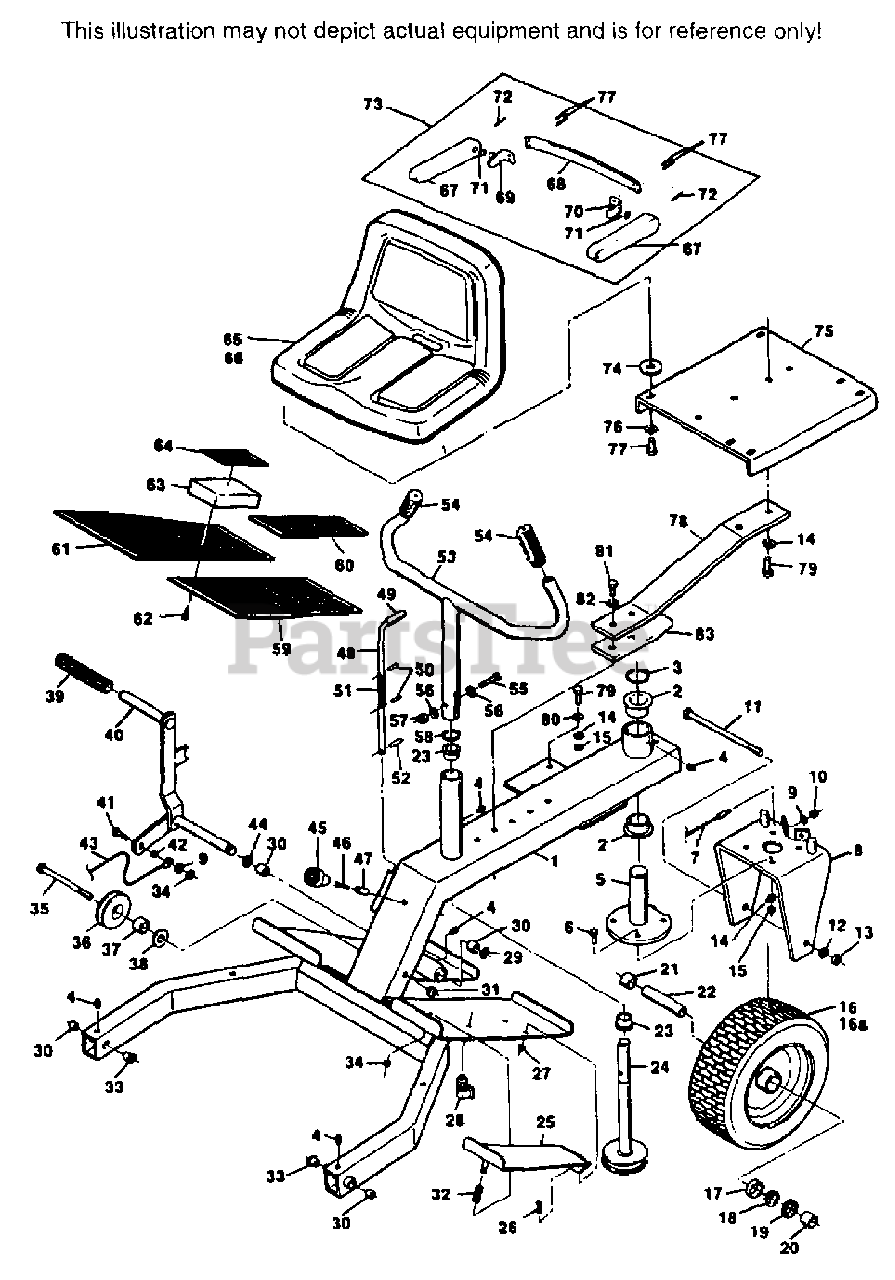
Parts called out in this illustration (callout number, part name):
1	STEERING FRAME
2	BRONZE BEARING
3	RETAINING RING, 1-1/8 EXT. BASIC
4	GREASE FITTING, 1/4-28 STR.
5	REAR WHEEL PIVOT
7	STEERING CABLE
8	REAR WHEEL YOKE
9	LOCKWASHER, 3/8 INT. TOOTH
10	HEX JAM NUT, 3/8-24 UNF
11	HEX HEAD BOLT, 5/8-11 X 9"
16	WHEEL ASSY(INCLUDES 16A-19)
16A	RIM ONLY
17	BEARING CUP
18	BEARING CONE
19	GREASE SEAL
20	SPACER, SHORT
21	SPACER, LONG
22	REAR WHEEL SLEEVE
23	BRONZE BEARING
24	STEERING SHAFT
25	SAFETY PEDAL
26	FLAT HEAD SCREW, #10-32 X 3/4 SLOTTED
27	HEX NUT, #10-32, ELASTIC STOP
28	FOOT SAFETY SWITCH
29	RETAINING RING, 3/4 EXT. "E"
30	BRONZE BEARING
31	HEX NUT, 1/2-13, ELASTIC STOP
32	SPRING, FOOT SAFETY SWITCH
33	BRONZE BEARING
35	HEX HEAD BOLT, 1/2-13 X 5-1/2"
36	WINCH CABLE PULLEY(INCLUDES 37)
37	BRONZE BEARING
39	SLEEVE, FOOT PEDAL
40	FOOT PEDAL WELDMENT
42	SLEEVE
43	FOOT CABLE ASSEMBLY
44	WASHER, 49/64 X 1-1/4 X 16 GA.
45	BUMPER STOP COVER
47	BUMPER STOP
48	PARKING BRAKE LEVER(INCLUDES 49)
49	GRIP
51	SPRING
53	STEERING HANDLE(INCLUDES 54)
54	GRIP
56	WASHER, 11/32 X 11/16 X 16 GA.
58	RETAINING RING, 7/8 EXT. BASIC
59	PAD - LH
60	PAD, SAFETY PEDAL
61	PAD - RH
63	HEEL REST
64	PAD, HEEL
65	SEAT ASSEMBLY(INCLUDES 66-72, 77)
66	SEAT ONLY
67	ARM REST
68	BACK STRAP
69	MOUNTING BRACKET - RH
70	MOUNTING BRACKET - LH
71	WAVE WASHER
72	SET SCREW 3/8-16 X 3/4 FLAT POINT
73	ARM REST KIT(INC. 67,68,69,70,71,72,78)
74	WASHER, 13/32 X 1-1/2 X 7 GA.
75	SEAT PLATE
76	LOCKWASHER, 5/16 SPRING
78	SEAT SUPPORT SPRING
80	WASHER, 13/32 X 13/16 X 16 GA.
82	LOCKWASHER, 7/16" SPRING
83	REINFORCEMENT, SEAT SPRING
